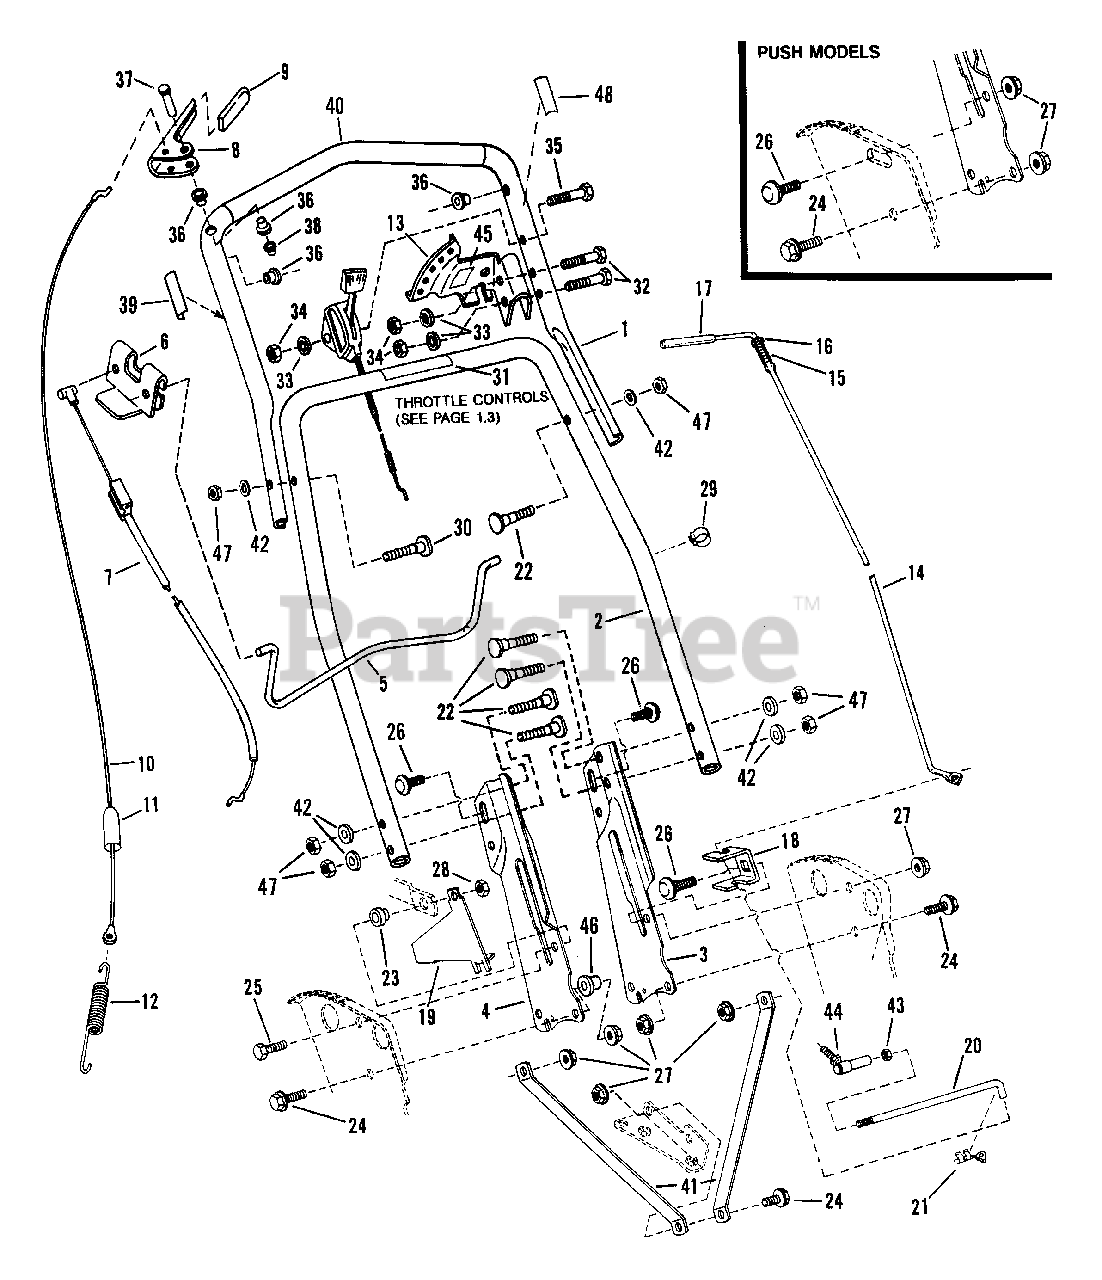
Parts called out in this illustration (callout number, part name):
1	HANDLE, Upper
2	HANDLE, Middle
3	HANDLE, Lower Right Hand
4	HANDLE, Lower Left Hand
5	BAIL, OPC Control (12.2" Wide)
6	CLIP, Blade Control
7	CABLE, Blade Control
8	HANDLE, Wheel Drive
9	GRIP, Wheel Drive Handle
10	CABLE, Clutch Pull(Z-Bend) 38.25"
11	COVER, Vinyl
12	SPRING, Clutch
13	SECTOR, Speed
14	LEVER, Speed Control 38" Long
15	SPRING, Speed Control
16	WASHER, 3/8" Flat
17	GRIP, Speed Control Handle
18	ANCHOR, Speed Control
19	GUIDE, Lower V-Belt
20	ROD, Transfer
21	CLIP, Transfer Rod
22	BOLT, 5/16-18 x 1-1/2" Curved Head
23	BUSHING, Differential
24	BOLT, 5/16-18 x 3/4" Flange Lock
25	SCREW, 5/16-24 x 1" Hex Cap
26	BOLT, 5-16-18 x 5/8" Carriage
27	NUT, 5/16-18 Hex Flange Lock
28	NUT, 5/16-24 Center Lock
29	CLIP, Wiring Harness
30	SCREW, 1/4-20 x 1-7/8" Curved Head
31	DECAL, Blade Control
32	SCREW, 1/4-28 x 1-3/8" Hex Cap
33	WASHER, 1/4 internal Tooth Lock
34	NUT, 1/4-28 Hex
35	SCREW, 1/4-28 x 1-3/4" Hex Cap
36	BUSHING
37	PIN, Clutch Handle
38	NUT, Push
39	DECAL, Blade Control
39	DECAL, Wheel Control
40	GRIP, Foam
41	STRAP, Handle
42	WASHER, 5/16 Internal Tooth Lock
43	NUT, 1/4-28 Hex
44	JOINT, Ball
45	DECAL, Speed Selector
46	NUT, 5/16-18 Tee
47	NUT, 5/16-18 Hex
48	DECAL, Blade Control
